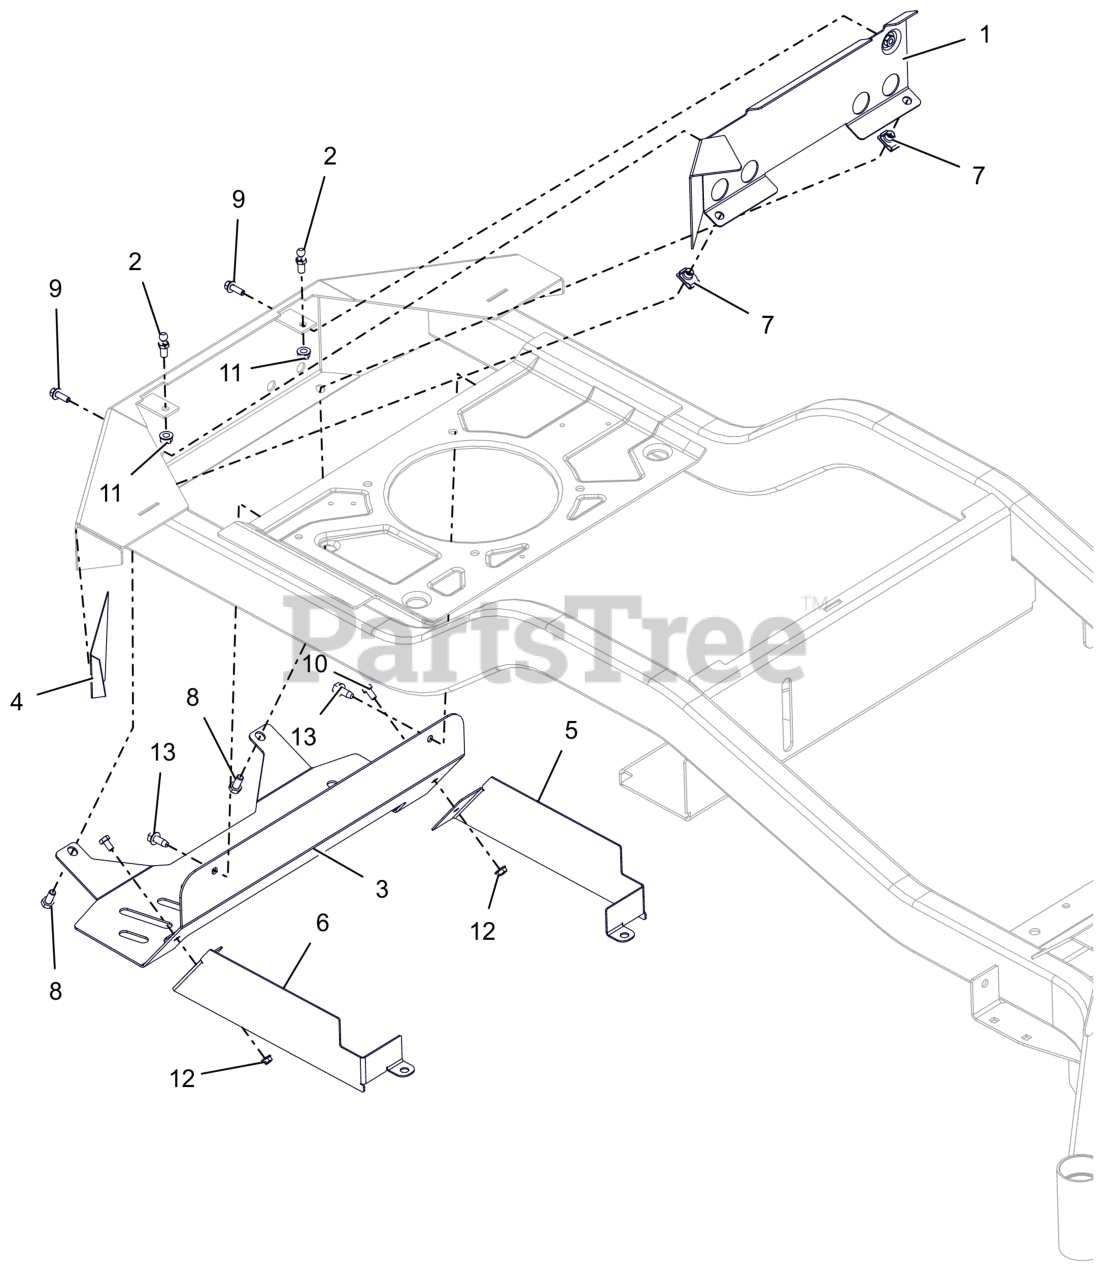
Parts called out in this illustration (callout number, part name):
1	WMT, HEAT BAFFLE
2	STUD- BALL
3	SHIELD, HEAT (HD)
4	TAPE, HEAT DEFLECTOR
5	GUARD,REAR CLUTCH LH
6	GUARD,REAR CLUTCH RH
7	NUT-CLIP RETAINER 5/16-18X.56
8	BLT,HEX .31-18X.75 G5 ZCC
9	BLT,HEX-FLG .25-20X.75 G5 BFP
10	BLT,HEX .25-20X.50 G5 ZCC
11	NUT,LK-CTR-FLG .31-18 GF ZCC
12	NUT-LK-TOP-FLG .250-20 GF ZCC
13	SCR,TAP .312-18X.75 HWH TR ZCC
